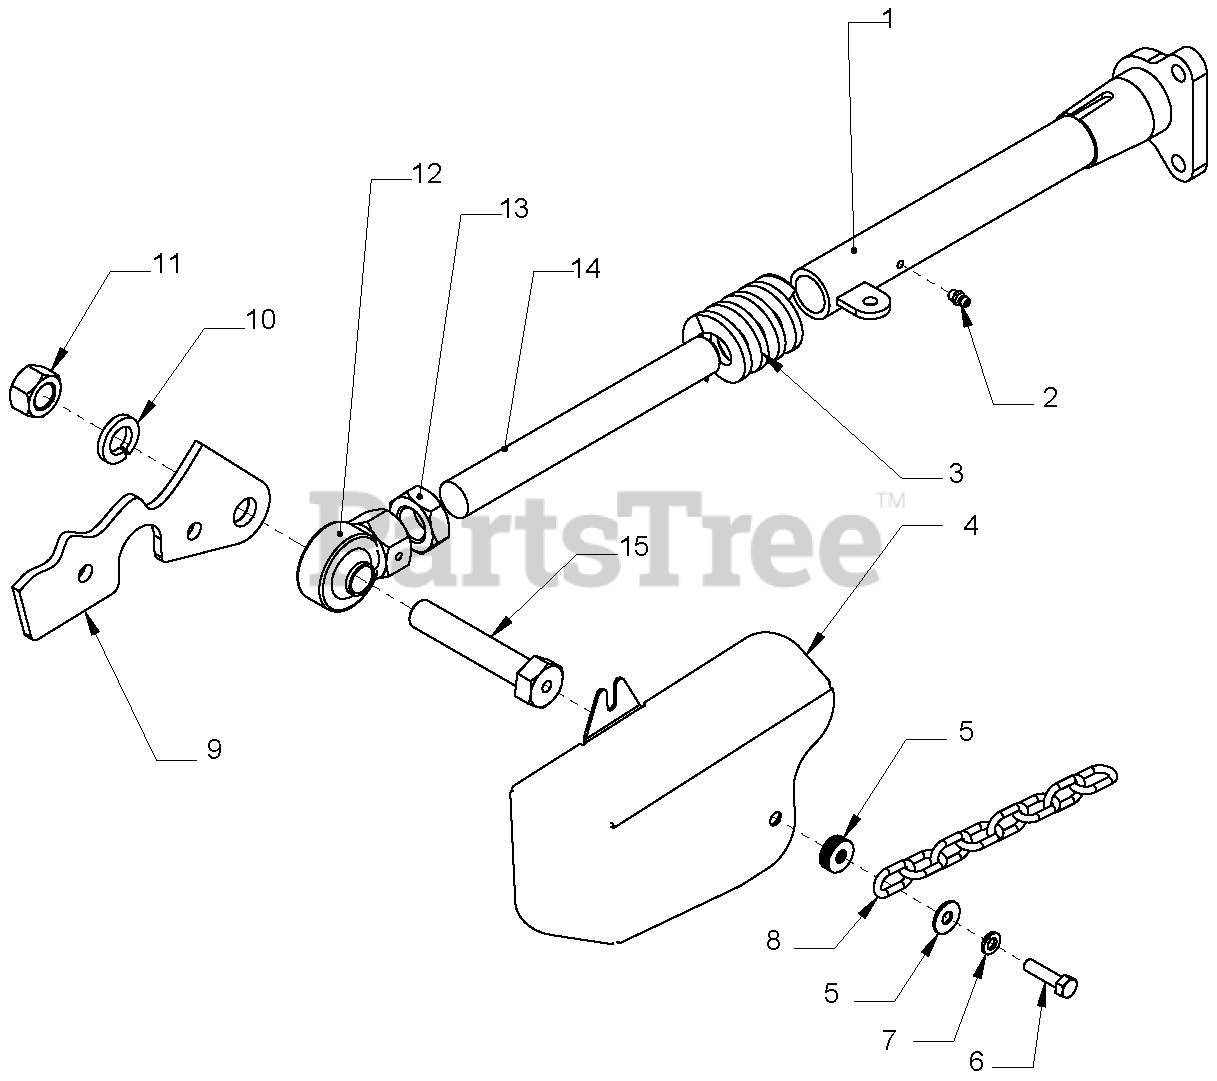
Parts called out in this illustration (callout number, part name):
1	Telescoping Arm
2	Grease Fitting, 1/4-28
3	Die Spring, Compression
5	Washer, Flat 5/16 USS CP
6	Cap Screw, Hex Head 5/16-18 x 1-1/4
7	Washer, Lock 5/16 CP
8	Safety Chain, 8 Links
10	Washer, Lock, 3/4 CP
11	Nut, Hex 3/4-10 CP
12	Ball Socket Weldment
13	Jam Nut, 1-8 Nyloc
14	Shaft, Telescoping Arm
15	Pivot Bolt
